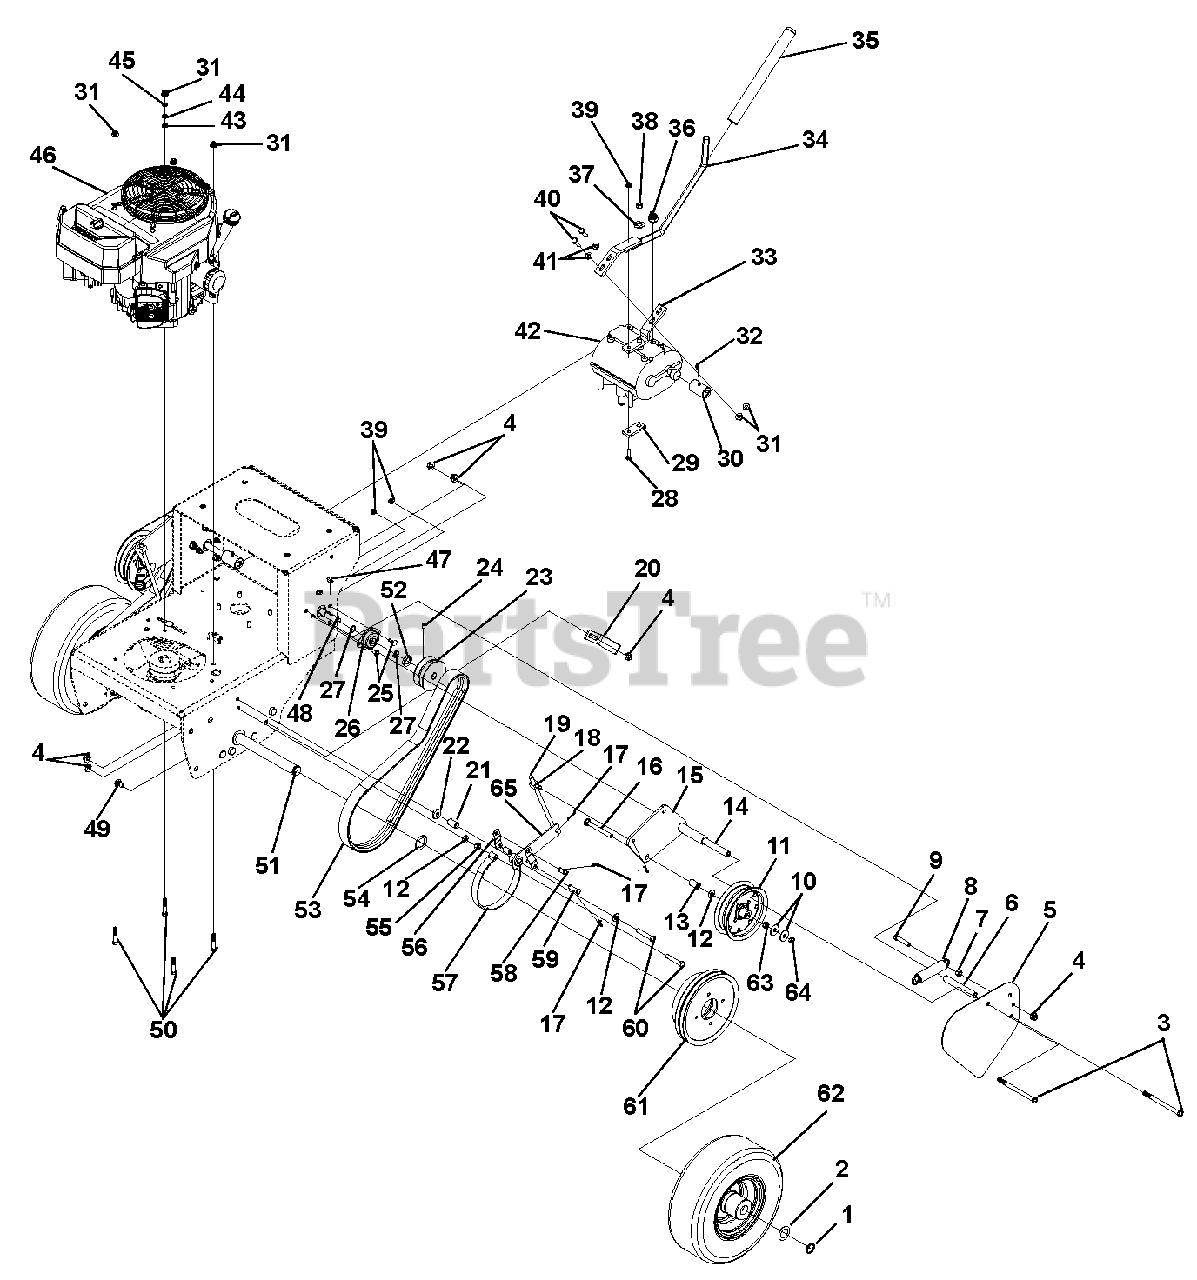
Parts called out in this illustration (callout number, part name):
1	Ring-Retaining-External 1.00 x .078
2	Washer, Flat-Steel 1.010 x 1.505 x .062
3	Bolt, .38-16 x 5.00 Hex 5
4	Nut, .38-16 Nyloc Flange
5	Cover, Traction Belt
6	Bushing,S.385 x .610 x 4.32 Steel
7	Nut, .38-16 Standard Hex Grade 5
8	Spring-Tension .105 x 1.00 x 5.0
9	Bolt, .38-16 x 1.75 Hex 5
10	Washer, Flat Steel .375X1.125X.065
11	Pulley, Flat 5.0 x .38 w/BRG
12	Washer, .406 x .813 x .065 Flat
13	Bushing, Sleeve .375 x .625 x .1.000
14	Bushing, S.385 x .610 x 4.32 Steel
15	Weldment, Wheel Clutching Arm-Left Hand
16	Bolt, Round Head Square Neck .38-16 x 3.5 Grade 5
17	Pin, Hair
18	Swivel, .38-24
19	Rod, Brake Actuating
20	Plate, Belt Finger
21	Bushing, S.391 x .622 x .95 St
22	Washer, Flat Steel .406 x 1.00 x .188
23	Sheave, Drive 3.25 OD x .625 ID
24	Screw, Set .31-18X.38 Socket Head
25	Bolt, Round Head Square Neck .25-20 x .750 Grade 5
26	Bearing, Flange .625 x 1.875 x .797
27	Ring, Retaining-External .579 x .035
28	Bolt, .25-20 x 1.00 Hex 5
29	Plate, Shift
31	Nut, .31-18 Nyloc Flange
32	Fitting, .25-28 STRGT Grease Zerk
33	Bracket, Shift Lever
34	Welment, Shift Lever
35	Grip, Handlebar
36	Switch, Nuetral Start (N.O.)
37	Washer, Locking .375 x .130
38	Nut, Locking-Center .375-24
39	Nut, .25-20 Nyloc Flange
40	Bolt, .3125-18 x 3.25 Hex 5
41	Washer, Flat Steel .344 x .688 x .065
42	Transmission
43	Washer, .313 Medium Spring Lock
44	Nut, Locking-Center Jam .31-18
45	Washer, Locking-EXT .326 x .599 x .031
46	Engine, KAWI FH381V KAI 13HP (410, 411)
47	Key, Woodruff .19 x .75 HRD#9
48	Shaft, Half
49	Bolt, Round Head Square Neck .38-16 x .750 Grade 5 LN
50	Bolt, .3125-18 x 1.75 Hex 5
51	Shaft, Axle
52	Washer, Flat .765 x 1.125 x .187
53	Belt, Gear Drive 49" Elbow COG
54	Washer, Hard-Thrust 1.007 x 1.542 x .062
55	Nut, .38-16 Standard Hex Grade 5
56	Link, Brake Arm
57	Assembly, Brake Band, Pro
58	Pin, CVS .375 x .750 x .516
59	Pin, Clevis .38 x 1.25
60	Bolt, .38-16 x 2.00 Hex 5
61	Assembly, Pulley and Drum
62	Assembly, Wheel And Tire 6 x 3.5 (410)
63	Locknut, .38-16 Center
64	Nut, Locking-Jam-Center .375-16
65	Weldment, Brake Actuating Lever
